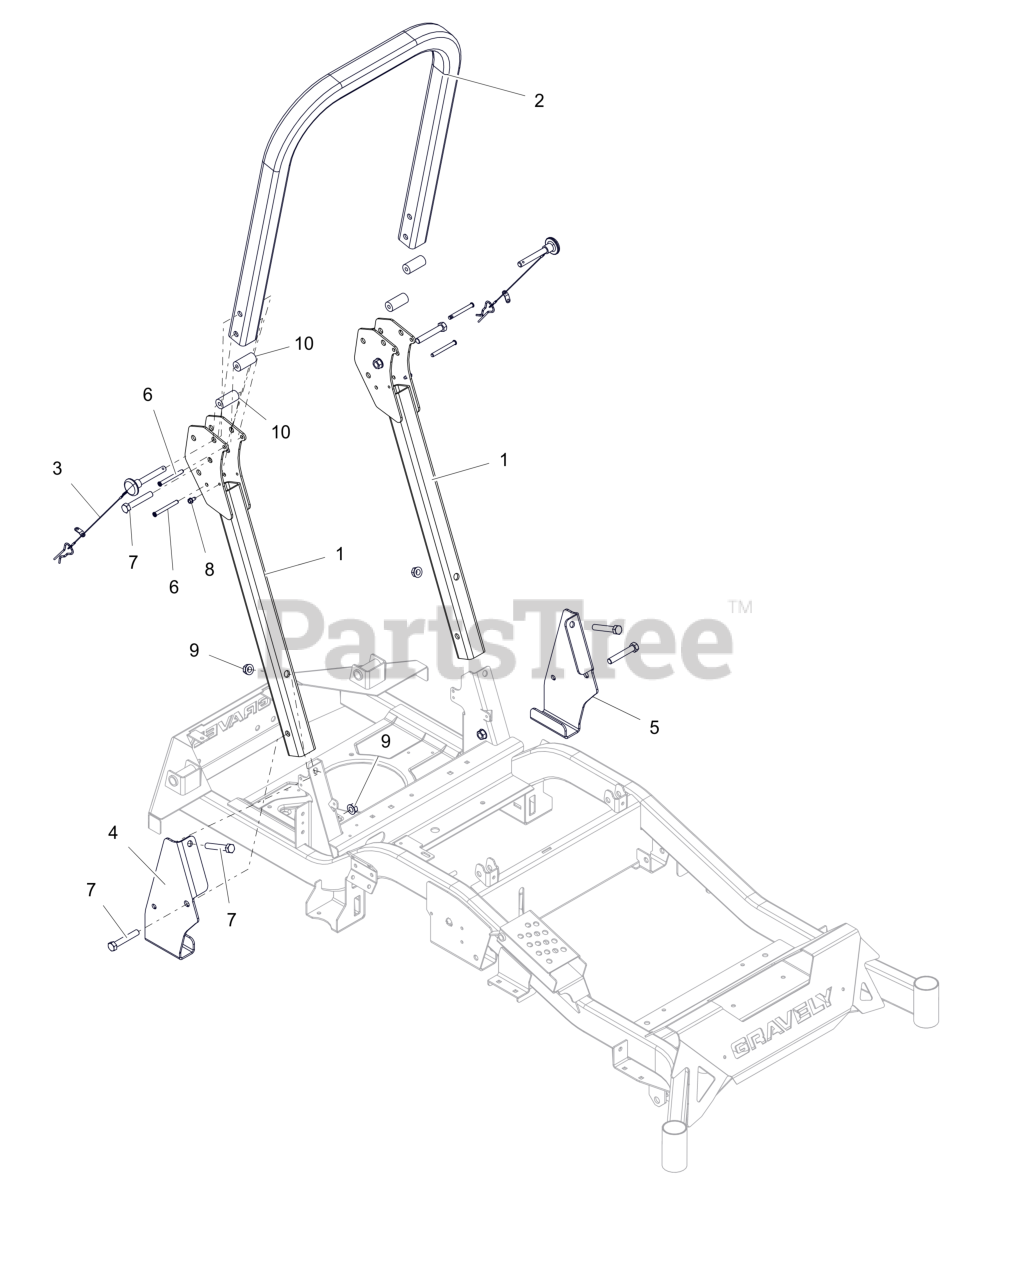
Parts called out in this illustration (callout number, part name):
1	ROPS, REPLACEMENT
2	HOOP, PT Z & ZX ROPS
3	PIN, ROPS W/LANYARD
4	BRKT, ROPS SUPPORT - RH
5	BRKT, ROPS SUPPORT -LH
6	PIN, SLIC .312 X 2.570
7	BLT, HEX .50-13X3.00 G5 ZCC
8	SCR-TAP .25-20X.50 HWH ZCC
9	NUT-LK-CTR-FLG .500-13 GG ZCC
10	BUMPER, ROPS ANTI-VIBRATION
